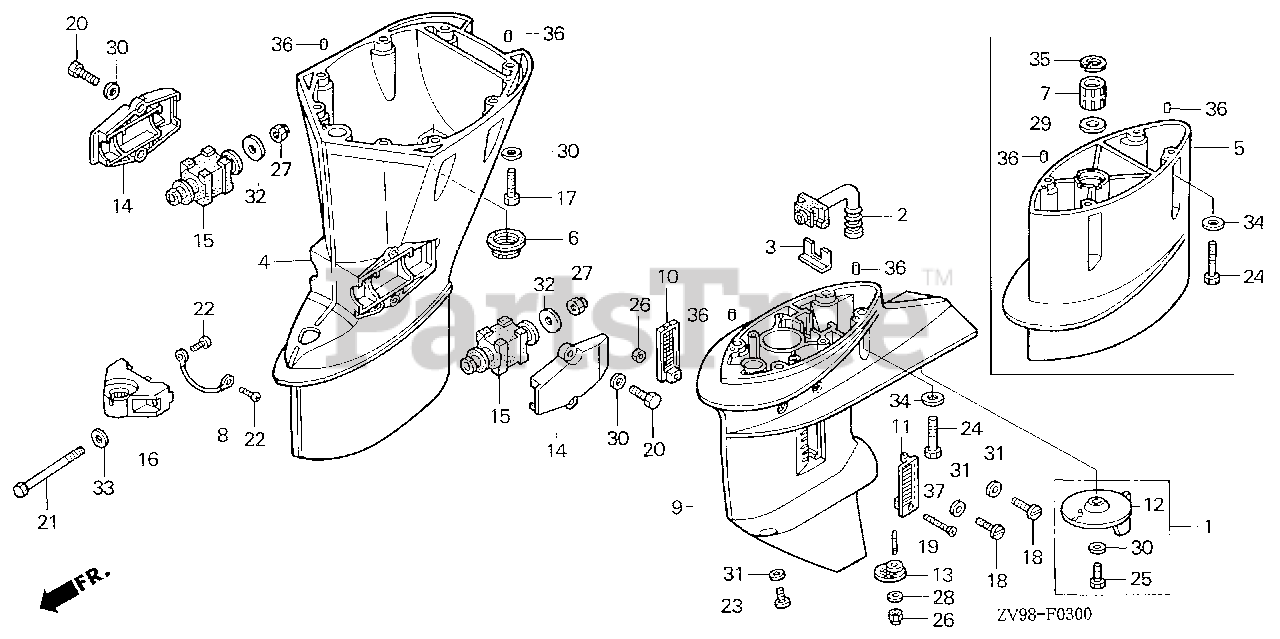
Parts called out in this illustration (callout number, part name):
1	TAB KIT, TRIM
2	TUBE, WATER (LOWER)
3	PLATE, RUBBER SETTING
4	CASE, EXTENSION *NH282MU* (S) (OYSTER SILVER METALLIC-U)
5	SEPARATOR, EXTENSION *NH282MU* (UL) (OYSTER SILVER METALLIC-U)
6	RUBBER, DRAIN PLUG
7	BUSH, VERTICAL SHAFT
8	WIRE, LEAD (1.5X116MM)
9	CASE, GEAR *NH282MU* (OYSTER SILVER METALLIC-U)
10	SCREEN, R. WATER
11	SCREEN, L. WATER
13	SCREEN, WATER (LOWER)
14	HOUSING, R. MOUNTING (LOWER) *NH282MU* (OYSTER SILVER METALLIC-U)
15	RUBBER, MOUNT (LOWER)
16	HOUSING, CENTER MOUNTING (LOWER) *NH282MU* (OYSTER SILVER METALLIC-U)
17	BOLT, HEX. (8X35)
18	BOLT, OIL CHECK (8X8)
19	BOLT, STUD (5X16)
20	BOLT, HEX. (8X25)
21	BOLT, HEX. (12X162)
22	SCREW, PAN (6X8)
23	BOLT, DRAIN PLUG (8MM)
24	BOLT, HEX. (10X40)
25	BOLT, HEX. (8X20)
26	NUT, SELF-LOCK (5MM)
27	NUT, SELF-LOCK (12MM)
28	WASHER, PLAIN (5MM)
29	WASHER (20MM)
30	WASHER, PLAIN (8MM)
31	WASHER, NYLON (8MM)
32	WASHER, PLAIN (12MM)
33	WASHER, PLAIN (12MM)
34	WASHER, PLAIN (10MM)
35	CIRCLIP (INNER) (30MM)
36	PIN, DOWEL (6X10)
37	SCREW, OVAL (5X28)
